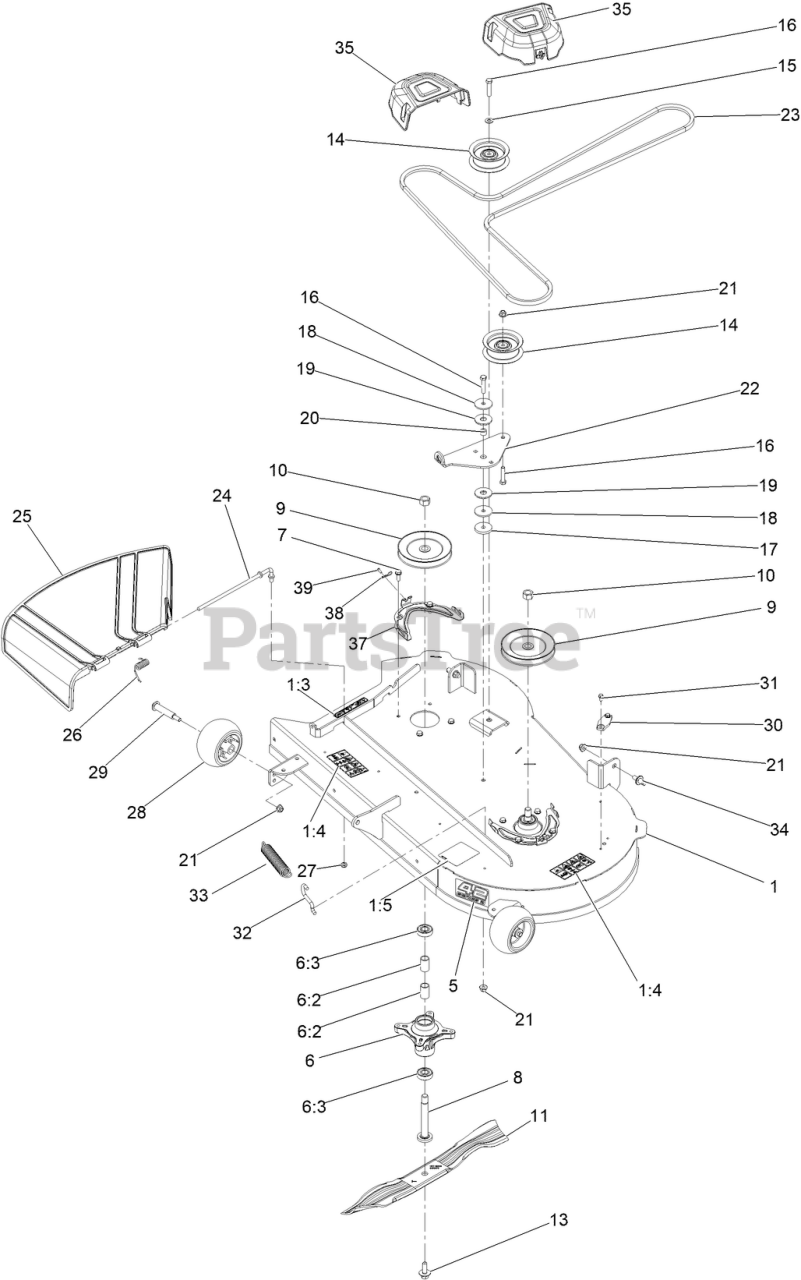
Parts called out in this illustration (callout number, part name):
1	42IN DECK AND DECAL ASM
1:3	Decal-Danger
1:4	DECAL-DANGER, DECK
1:5	DECAL-ROUTING, BELT
5	Decal-42 Series 2
6	SPINDLE ASM
6:3	BEARING-BALL
7	SCREW-TAPTITE
8	SHAFT-SPINDLE
10	NUT-HEX
11	BLADE-21.6 IN
13	Bolt-Blade, Sems
14	PULLEY-IDLER, FLAT
15	WASHER-FLAT
16	SCREW-HH
17	WASHER-PLAIN
18	WASHER-REBOUND
19	WASHER-FRICTION, COMPOSIT
21	NUT-HF, NI
22	Arm-Idler
23	V-BELT
24	ROD-PIVOT
25	DEFLECTOR-DISCHARGE
26	SPRING-TORSION
28	ROLLER-SCALP, ANTI
29	BOLT-SHOULDER
30	COVER-WASHOUT PORT
31	SCREW-HWH
32	Hook-Return Spring
33	SPRING EXTENSION
34	PIN-DECK
35	COVER-BELT
37	BRACKET-COVER, BELT
38	PIN-HAIR
